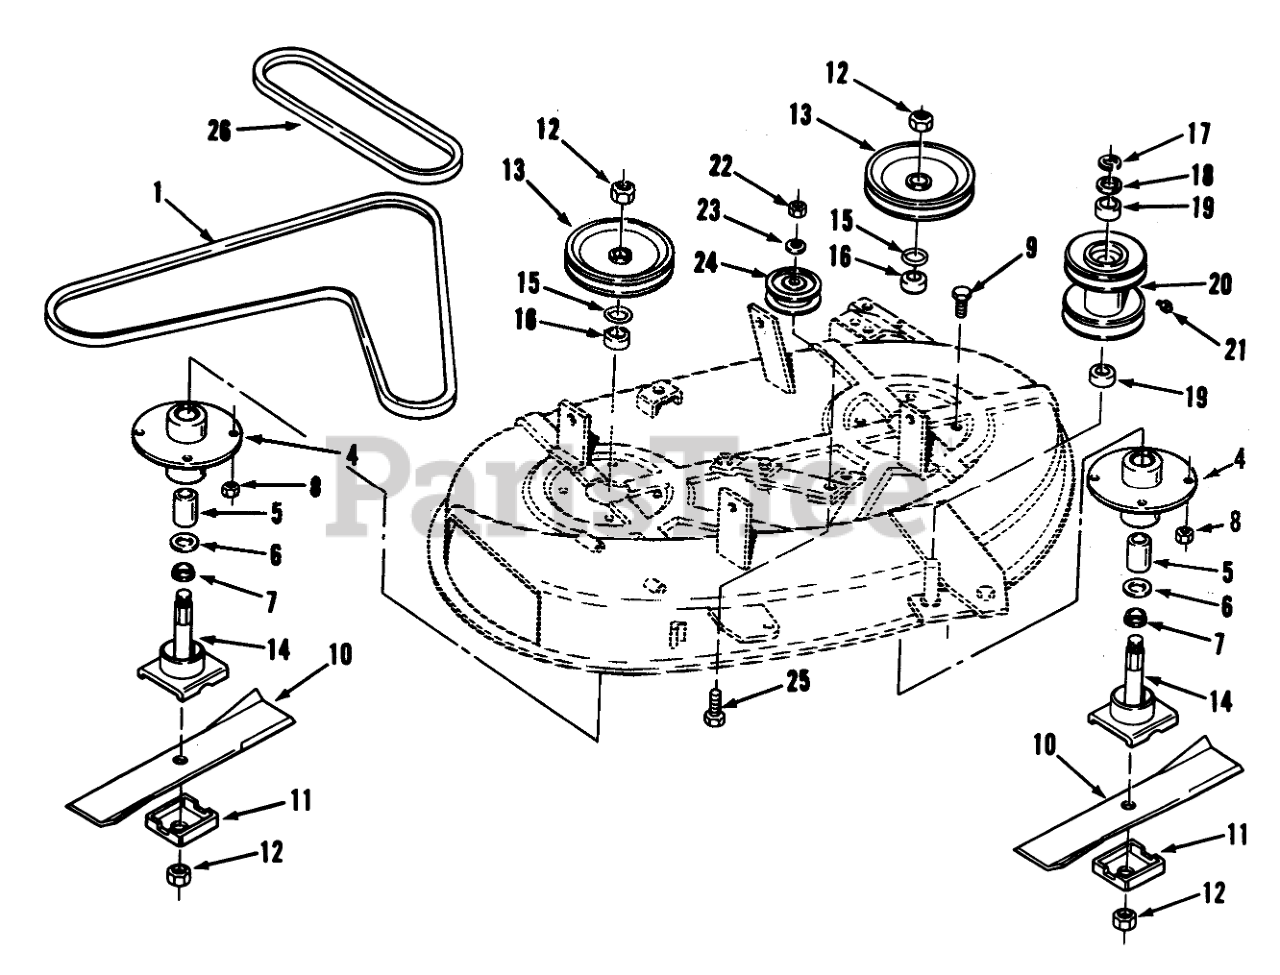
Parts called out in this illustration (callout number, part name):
1	V-BELT
4	Spindle
5	BEARING SPACER
6	RING-RETAINING
7	SPACER-SPINDLE
8	Nut
9	Bolt
10	Blade
11	Cup
12	NUT-LOCK NI
13	DECK PULLEY
14	Spindle Shaft Assembly
15	Washer
16	BEARING-BALL
17	RETAINING RING
18	O RING
19	BEARING-BALL
20	PULLEY-COUNTER SHAFT
21	Fitting-Grease
22	NUT
23	Washer
24	Pulley
25	Bolt
26	V-BELT
